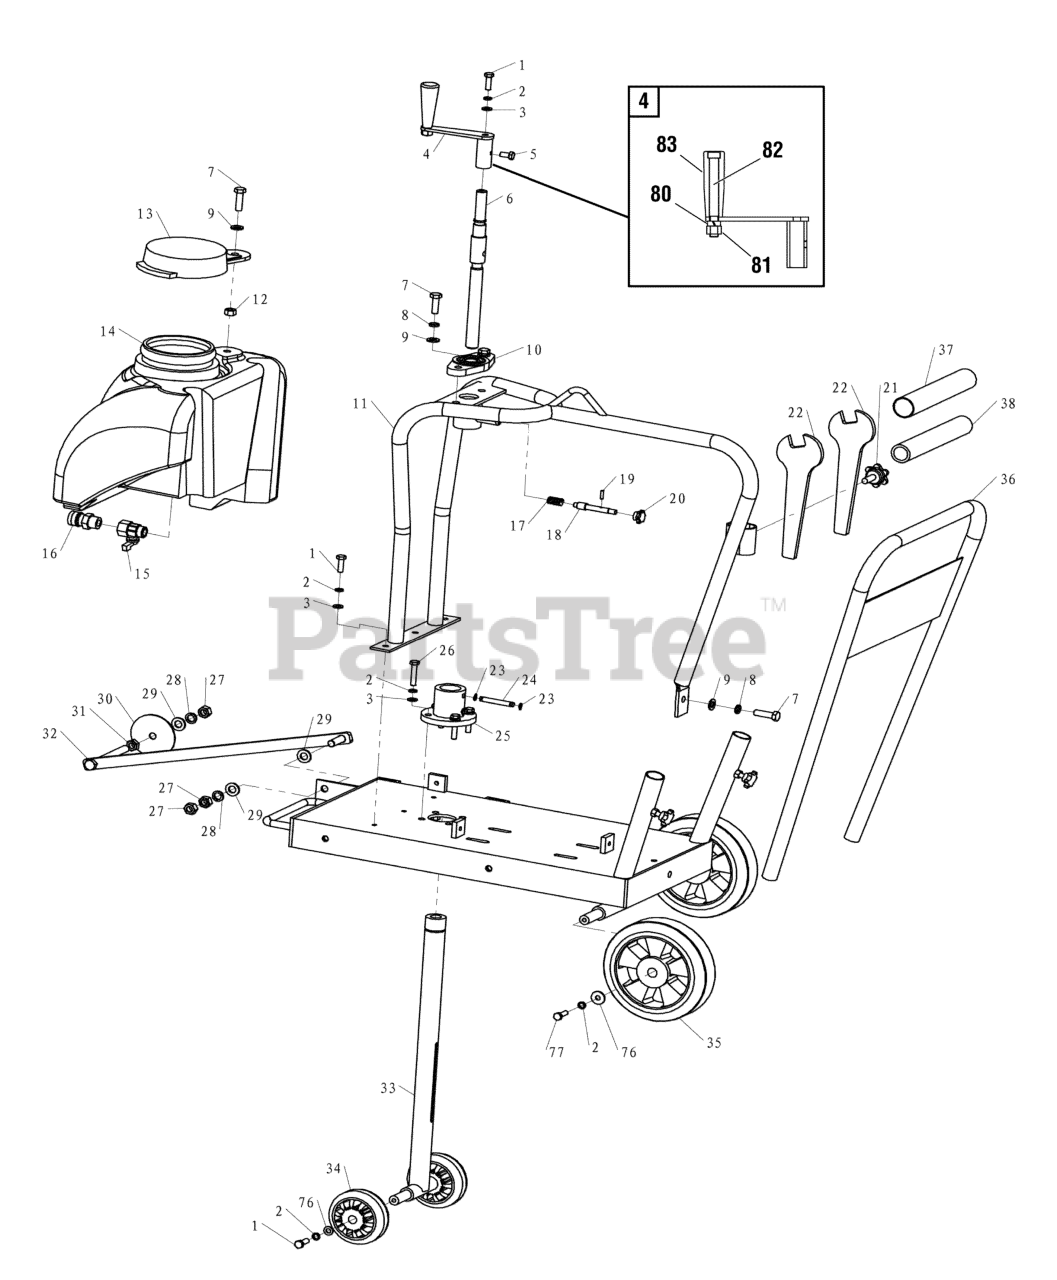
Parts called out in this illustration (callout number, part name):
1	BOLT, M8 x 25
2	WASHER, Spring, 8
3	WASHER, Flat, 8
4	HANDLE, Adjust, Blade Height
5	BOLT, M8 x 12
6	ROD, Threaded
7	BOLT, M10 x 35
8	WASHER, Spring, 10
9	WASHER, Flat, 10
10	BEARING
11	GUARD, Tank
12	BOLT, M10
13	COVER, Water Tank
14	WATER TANK
15	BALL VALVE, Brass,1/4"
16	QUICK CONNECTOR
17	SPRING
19	SPRING PIN
21	KNOB BOLT
22	SPANNER
23	RING, Retaining
25	PLATE, Guide
26	BOLT, M8 x 30
27	NUT, M12
28	WASHER, Spring, 12
29	WASHER, Flat, 12
30	WHEEL, Guide
32	ROD, Guide
33	CONNECTING ROD
34	WHEEL, Front
35	WHEEL, Rear
36	HANDLE
37	FOAM, Handle
38	SHEATH, Handle
76	WASHER
77	BOLT, M8 x 20
80	WASHER, 10
81	NUT, M10
82	BOLT, Lock
83	HANDLE
